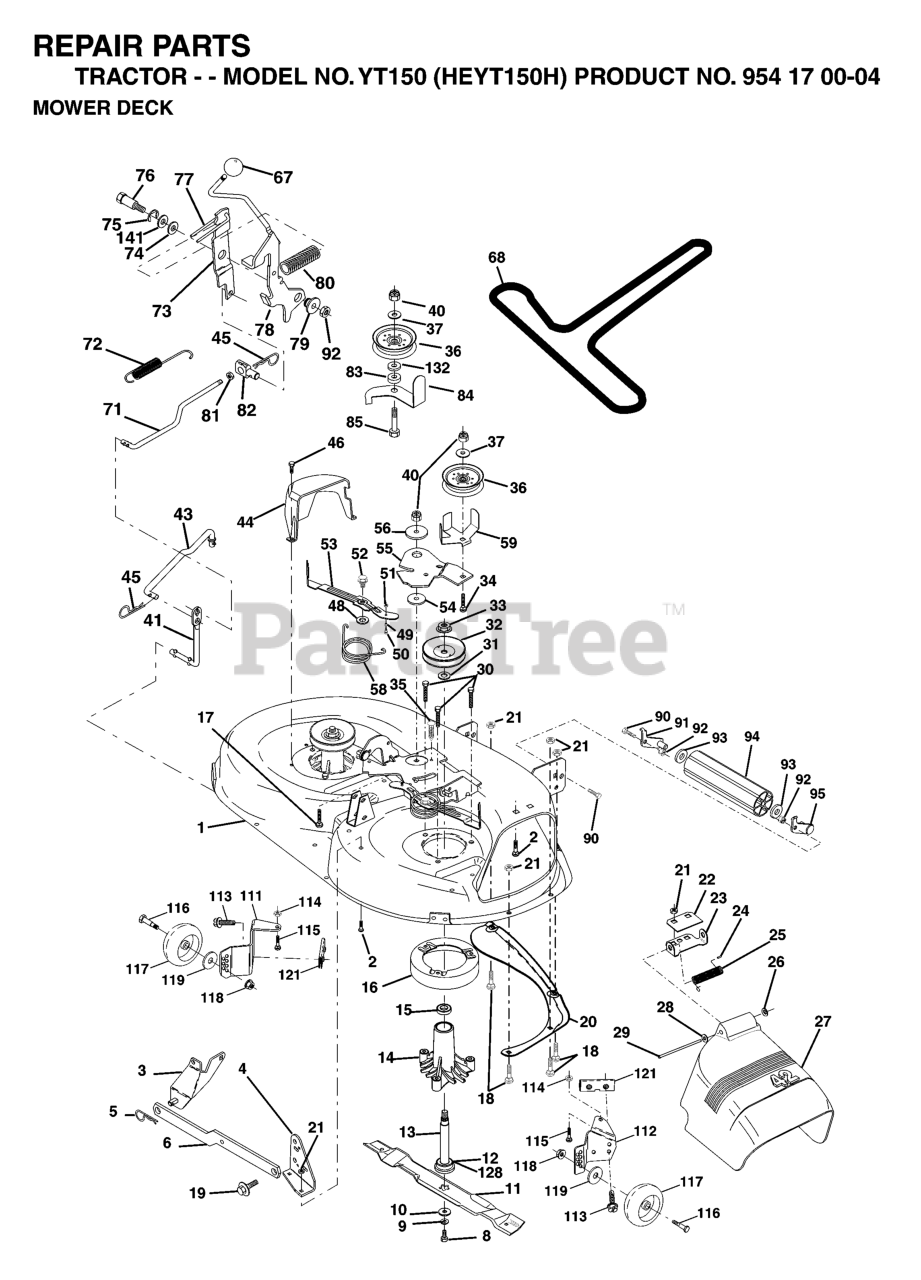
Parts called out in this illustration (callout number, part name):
1	DECK 42"
2	RP BOLT 5/16-18 X3/4 ZN/YEL GR
3	BRKT ASM SWAY BAR
4	BRKT DECK SW BAR
5	RETAINER-SPRNG RB
6	REAR SUSP ARM
8	BLADE BOLT
9	LOCKWASHER
10	WASHER.BLADE
11	Blade Mower 42" High Perf.
12	BEARING.BALL.#6204.(MANDREL)
13	SHAFT ASM VENT
14	HOUSING.MANDREL.VENTED (MACHD)
16	STRIPPER
17	BOLT
18	BOLT
19	BOLT SHD 5/16-18
20	BAFFLE.VORTEX
21	LOCKNUT
22	STIFFENER BRACKET
23	DEFLECTOR BRACKET
24	CAP-SLEEVE LT
25	SPRING TORSION
26	NUT PUSH M
27	SHIELD.DEFLECTOR.MOWER.42".BLK
28	Washer 11/32 x 5/8 x 16 Ga SD
29	ROD.HINGE
30	SCREW THDROL ROLLING WASHER HD
31	WASHER
32	PULLEY/MANDREL
33	NUT
35	FASTENER.XMAS.TREE
36	FLAT IDLER PULLEY
37	WASHER
43	CLUTCH ROD
44	GUARD MANDREL LH BLACK
45	RETAINER M
46	SCREW.1/4-20X5/8
49	ROLLER ASSY
52	BOLT.SHOULDER.5/16-18
53	ARM ASM PAD BRAD
54	HARDENED WASHER
55	ARM IDLER 42" MOWER LT/YT
56	SPACER RETAINER
59	GUARD, BELT
67	KNOB.CONTROL.7/16
68	V-BELT TRIPATH
71	CLUTCH ROD
72	RETURN SPRING
73	ARM CLUTCH SECONDARY
77	KEEPER SPRING
78	CLUTCH LEVER ASSY
79	BUSHING.FLANGE.E-RING.GROOVE
80	SPRING-CLUTCH (2 2 PW01)
81	NUT
82	TRUNNION.ADJUSTABLE.3/8-16
84	KEEPER.BELT.IDLER
85	BOLT
90	BOLT
91	BRACKET LH (A)
92	NUT
93	Washer 1 17/32 X 7/8 X 16 Ga
94	NOSE ROLLER
95	BRACKET RH (B)
111	BRACKET WHEEL GAUGE LH 42" DK
112	BRACKET WHEEL GAUGE RH 42" DK
113	SCREW.THDROL.5/16-18X3/4.TTY
114	NUT
115	BOLT.CARR.5/16-18X1/2
116	BOLT, SHOULDER
117	WHEEL GAGE DONUT
118	LOCKNUT
119	WASHER.5/16.FLAT.STE.STD.
121	BRACKET.EXTRUDED.GAGE.WHEEL
128	WASHER FELT
129	WASHER
131	BOLT D
132	Washer 13/32 x 1-3/8 x 13 Ga.
141	BEARING RACE
